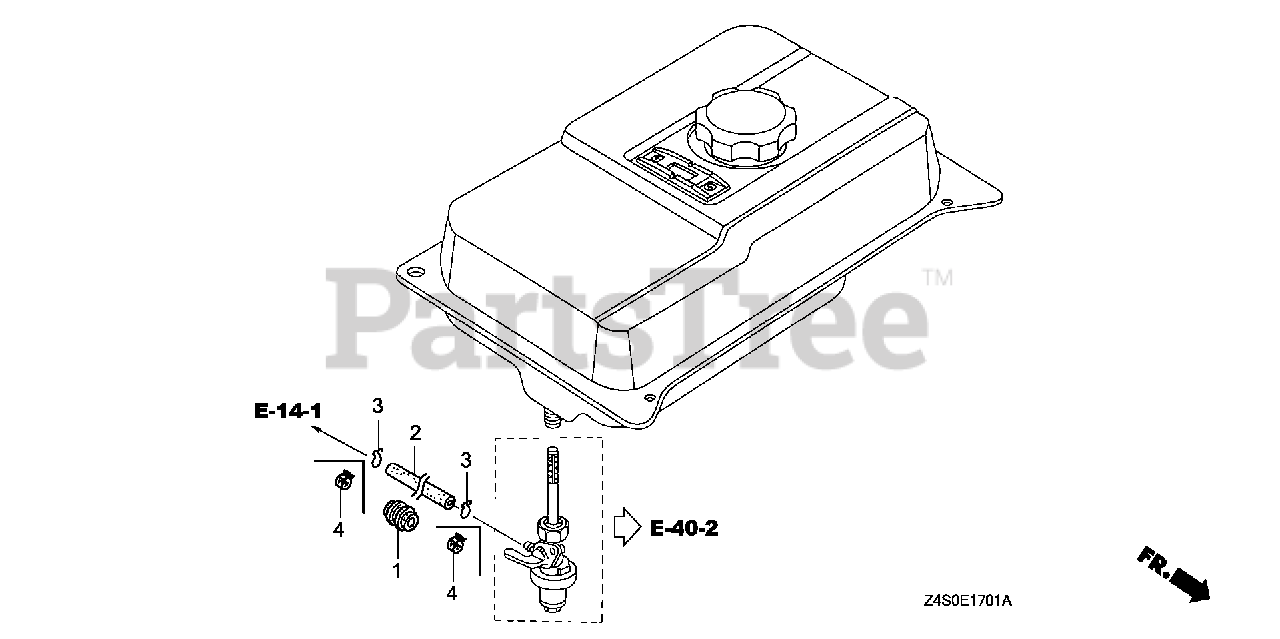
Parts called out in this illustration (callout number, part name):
1	RUBBER, FUEL (9X15X20)
2	TUBE, FUEL (4.5X140) (FKM)
2	BULK HOSE, FUEL (4.5X3000) (4.5X140)
3	CLIP, TUBE (B8)
4	CLAMP, TUBE (D8)
